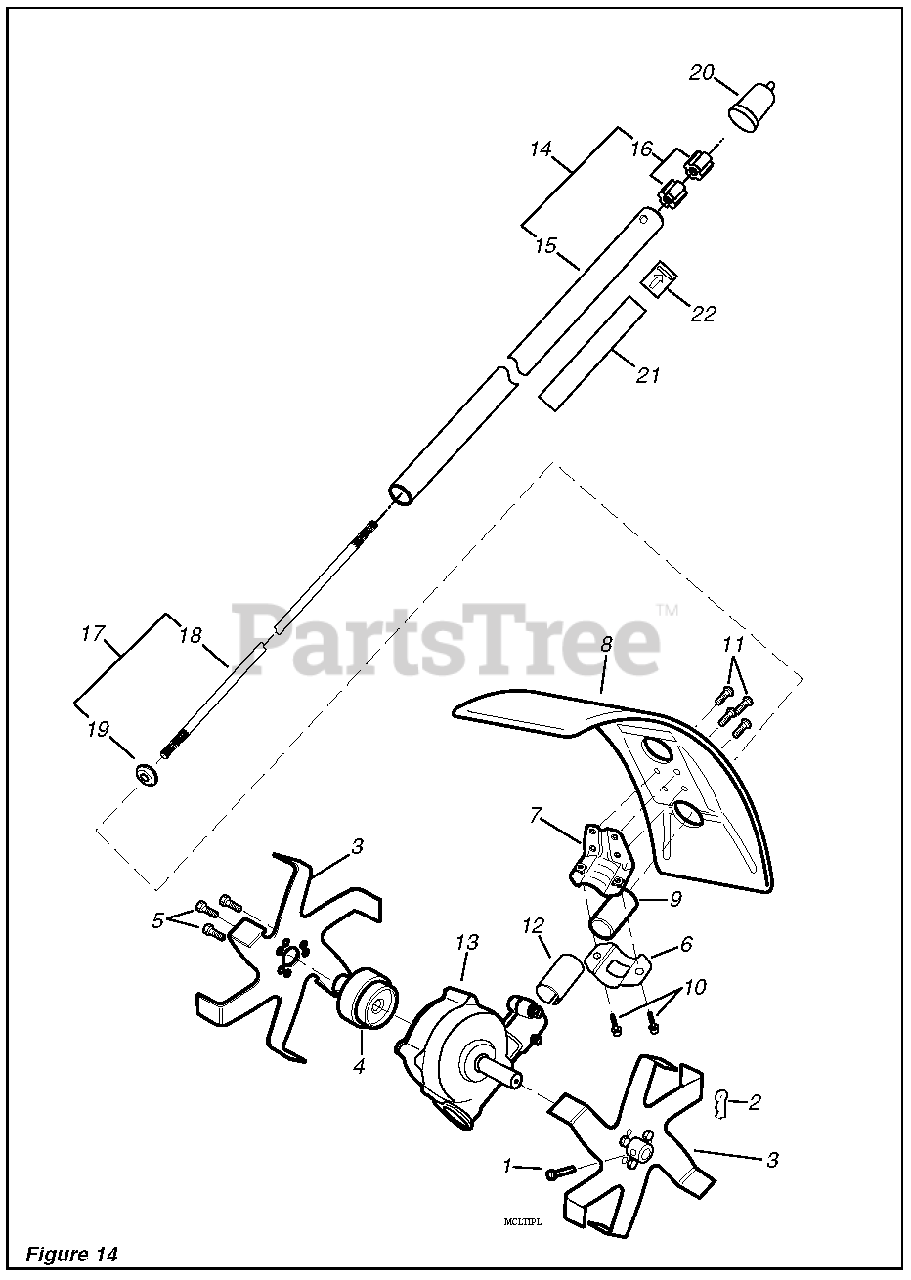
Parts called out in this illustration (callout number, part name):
1	LOCK PIN
2	RING, RETAINING
3	TINE
4	TINE HOLDER
5	SCREW
6	BRACKET, SHIELD
7	BRACKET, SHIELD
8	SHIELD, DEBRIS
9	COLLAR
10	SCREW
11	SCREW
12	SPACER
13	CASE, GEAR
14	PIPE ASSY - OUTER
15	PIPE - OUTER
16	BUSHING
17	MAIN PIPE ASSY
18	PIPE, MAIN
19	GROMMET
20	CAP
21	LABEL - CAUTION
22	LABEL - ALIGNMENT
